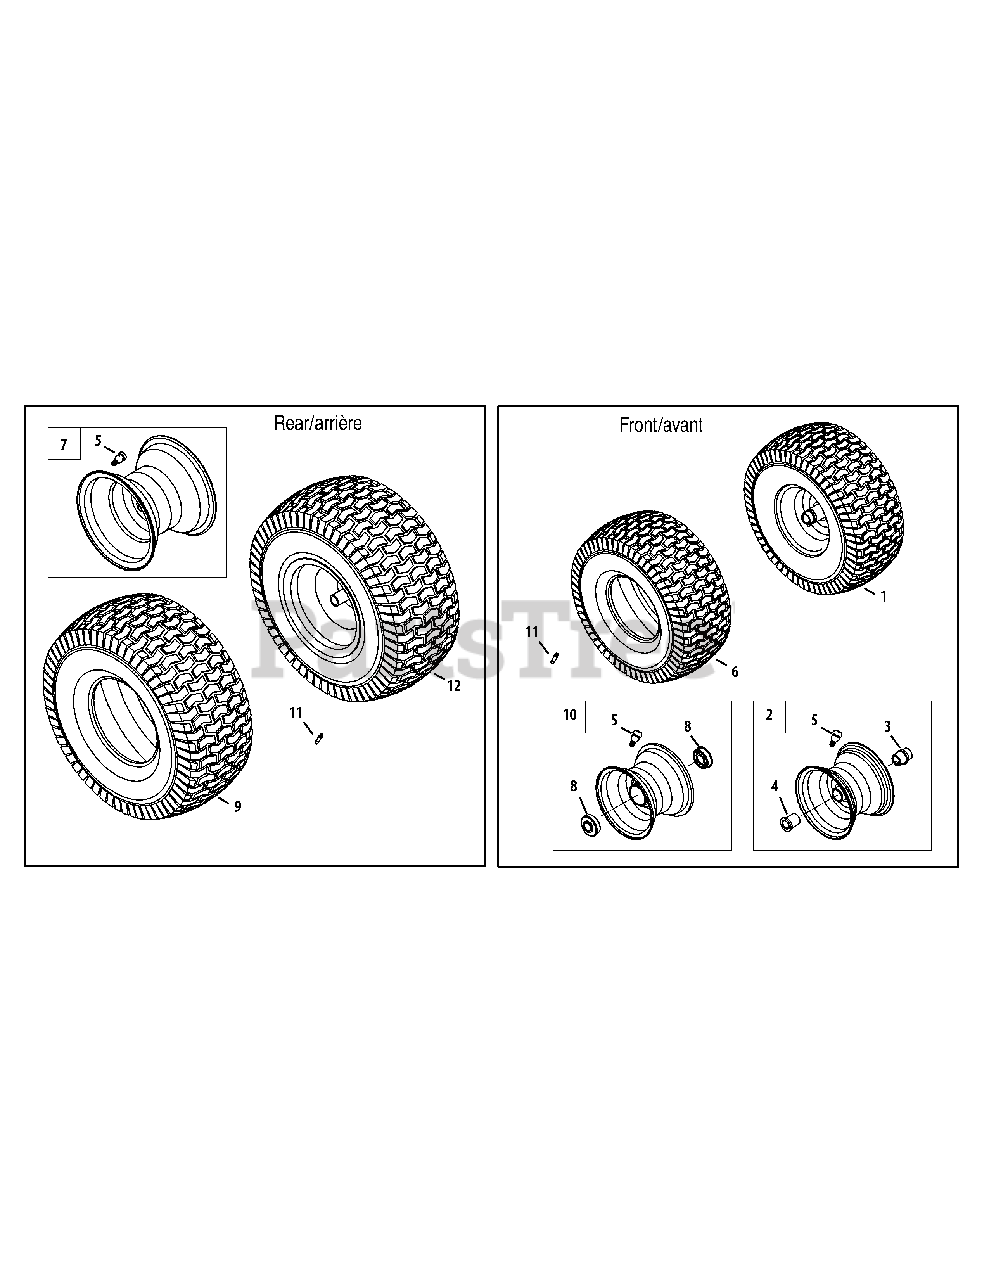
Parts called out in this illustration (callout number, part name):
1	Wheel Ass’y, 15 x 6 Ball Brg. (Grey)
2	Rim Ass'y, Plst. Brg.
3	Flg. Bearing .760 ID w/fitting
4	Flg. Bearing .760 x 1.0 x 1.20
5	Air Valve
7	Rim Ass'y, 8.0 x 7.0 x .750 (Grey)
8	Ball Bearing .750 ID x 1.750 OD
10	Rim Ass'y, Ball Brg. (Grey)
11	Grease Fitting
12	Wheel Ass'y, 20 x 8 (Grey)
12	Wheel Ass'y, 20 x 10 (Grey)
